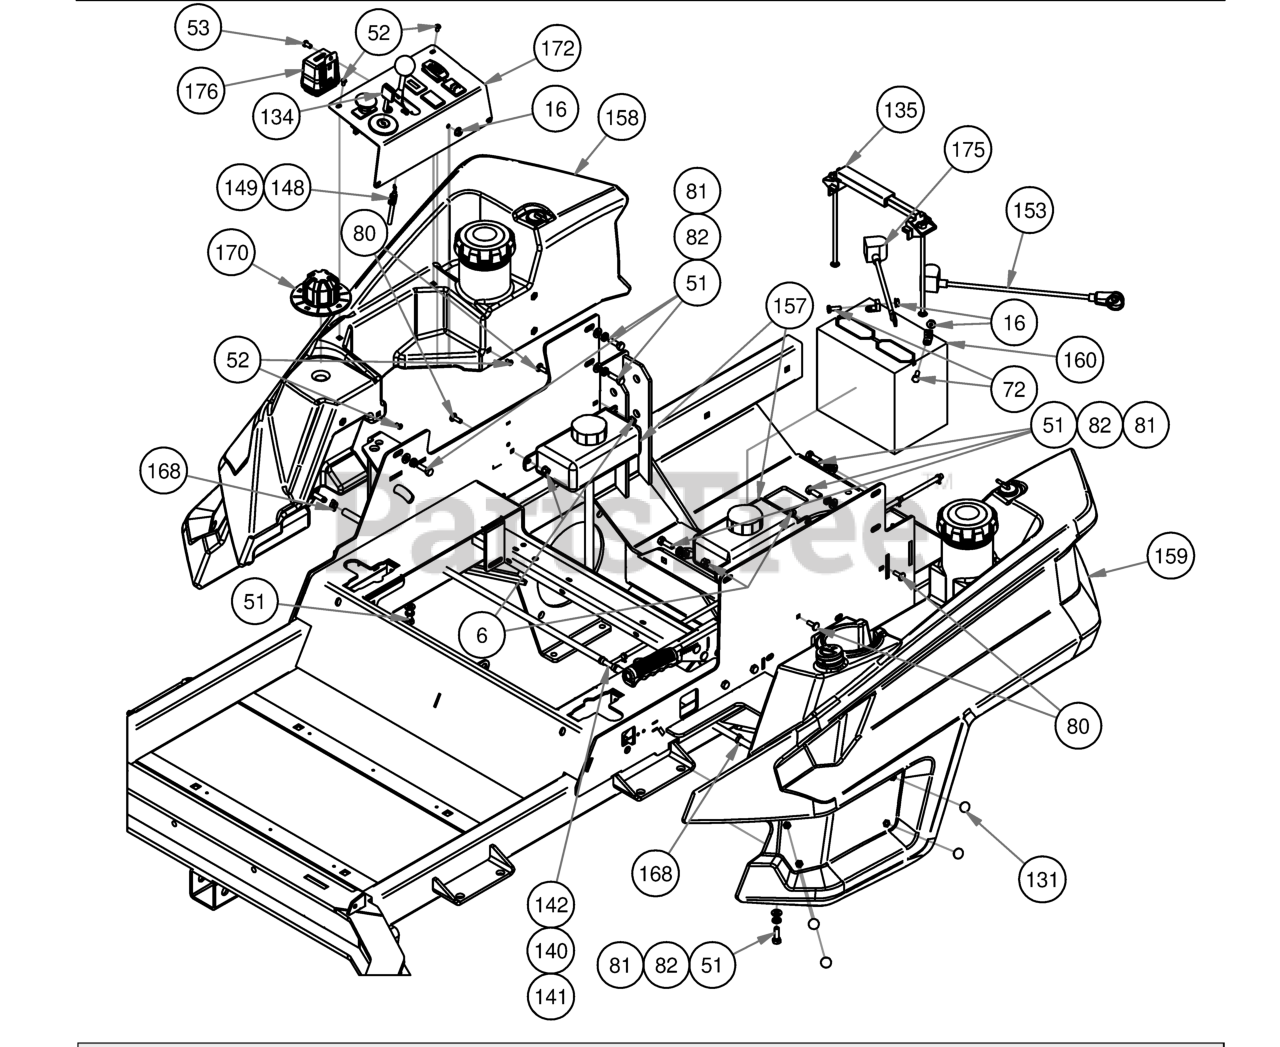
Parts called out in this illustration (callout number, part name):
6	1/4-20 Nylon Insert flange Nut
16	1/4-20 Hex Flange Nuts Zinc w/Serrations
51	5/16" x 1" Bolt
52	10-32 x 3/8" Button Socket Head Bolt
53	1/4" x 1/2" BS C/S 18-8 SS
72	1/4" x 3/4" Hex Bolt
80	1/4" x 3/4" Carriage Bolt
81	5/16" Flat Washer
82	5/16" Lock Washer
131	3/16 x .48 Christmas Tree Nylon Black
134	Ignition Key
135	Hold Down Assembly
140	2019 Rebel Rogue Renegade Fuel Line for Vanguard & Yamaha
141	2019 Rebel Rogue Renegade Fuel Line for Kohler
142	2019 Rebel Rogue Renegade Fuel Line for Kawasaki
148	Outlaw Throttle Cable
149	Throttle Cable for 36Hp Vanguard & FX1000 Kawasaki
153	14" Red Battery Cable-Base Outlaw
157	2019 Rebel Hydro Tank Assembly
158	2019 Right Rebel, Rogue, Renagade Fuel Tank (GAS)
159	2019 Left Rebel, Rogue, Renegade Fuel Tank (GAS)
165	2019 Rigid Frame
168	2 EAR CLAMP 12.5mm-15mm
170	2019 Rigid Deck Dial 1.5 to 5.5
172	Rebel/Rogue Control Panel Assy
175	Starter Cable
176	2019 Wiring Harness-Rebel/Rogue
